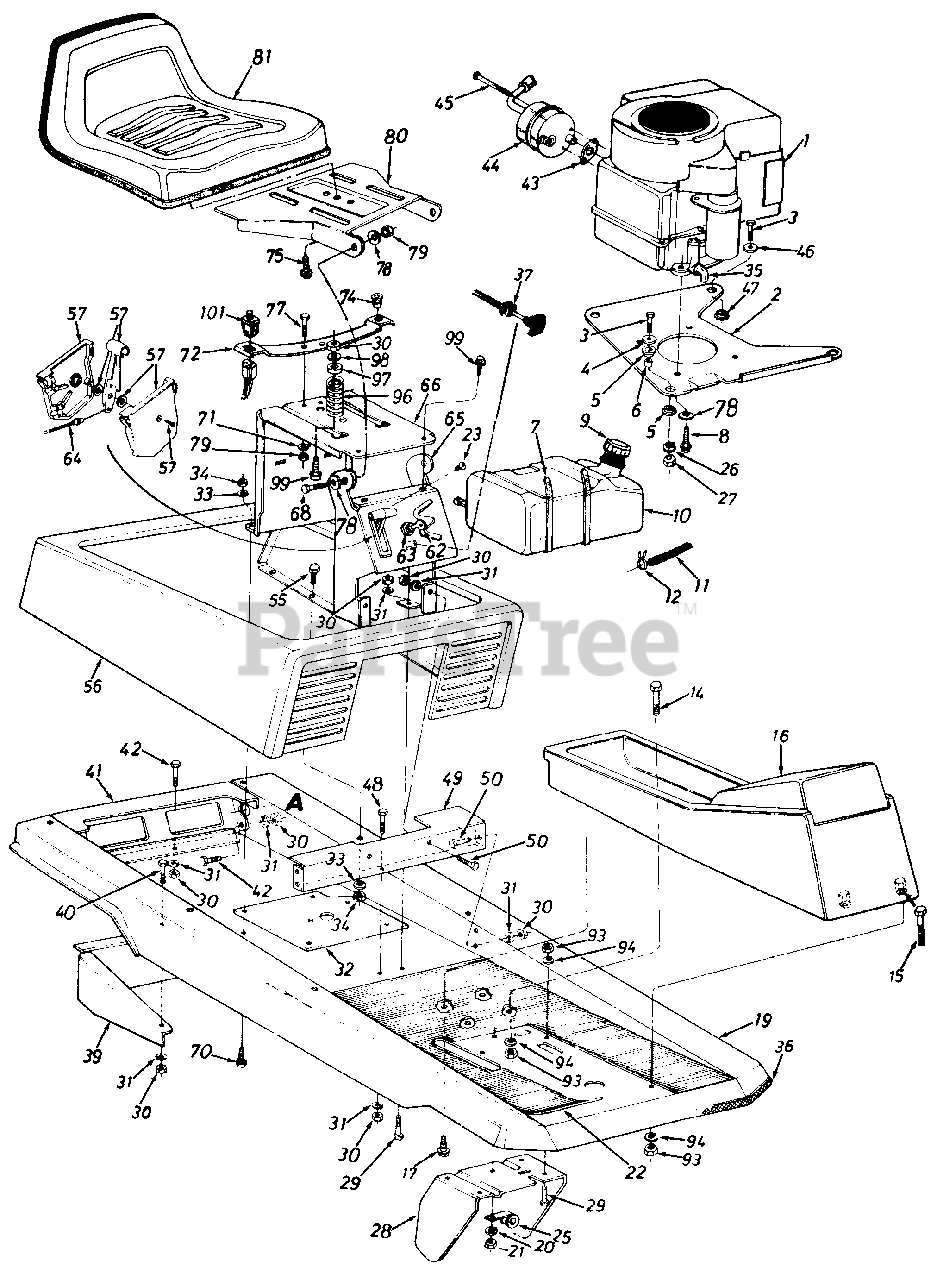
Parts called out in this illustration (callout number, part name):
1	Engine
4	Fl-Wash. .330" I.D. x 1.125" O.D.
5	Engine Mounting Grommet
6	Spacer .315" I.D. x .50" O.D. x.520" Lg.
7	Cable Tie 30.6" Lg.
8	Hex Wash. Hd. Self-Tap Scr. 3/8-16 x 1.25" Lg.
9	Gas Gauge
10	Fuel Tank (Black)
11	Gas Line-26 Inches
12	Hose Clamp-1/2" O.D. Tube
14	Hex Bolt 5/16-18 x 1.75" Lg.
15	Hex Bolt 5/16-18 x 2.0" Lg.
16	Front Console
17	Plastite Scr. 5/16 x 1.25 Lg.
19	Main Frame
20	L-Wash. 5/16" I.D.
21	Hex Nut 5/16-18 Thd.*
23	Truss Mach. AB-Tap Scr. #10 x .50" Lg.
26	L-Wash. 5/16" I.D.
27	Hex Nut 5/16-24 Thd.
28	Clutch-Brake Pedal Ass'y.
29	Hex Bolt 5/16-18 x .75" Lg
30	Hex Nut 5/16-18 Thd.
31	L-Wash. 5/16" I.D.
34	Hex Nut 1/4-20 Thd.*
35	90ø Elbow Male To Female
36	Trim Strip 18" Lg.
37	Choke Control
43	Exhaust Gasket
44	Muffler Ass'y.
45	Shld. Bolt
46	Fl-Wash. .33" I.D. x 1.25" O.D.
47	Flange Wash. .32" I.D. x .75" O.D.
48	Hex Bolt 5/16-18 x .75" Lg.
49	Seat Support & Frame Brkt.
50	Hex Bolt 5/16-18 x .75" Lg.
55	Hex Bolt 1/4-20 x .50" Lg.
56	Engine Cover Ass'y.
57	Throttle Control Box Ass'y.
62	Ignition Key
63	Ignition Switch
64	Throttle Control Wire
70	Hex Tap Scr. 1/4-20 x 1.0" Lg.
71	L-Wash. 5/16" I.D.
75	Hex Wash. Hd. Tap Scr. 3/8-16 x 3/4 " Lg.
77	Hex Bolt 5/16-18 x .75" Lg.
78	Bell-Wash. .345" I.D. x .88" O.D.
79	Hex Cent. L-Nut 5/16-18 Thd.
80	Seat Pivot Bracket
81	Seat Ass'y.
93	Hex Nut 5/16-18 Thd.
94	L-Wash. 5/16" I.D.
96	Compression Spring 2.61" Lg.
98	Fl-Wash. .344" I.D. x .875"
99	Hex Bolt 5/16-18 x 1" Lg. (Gr. 5)
